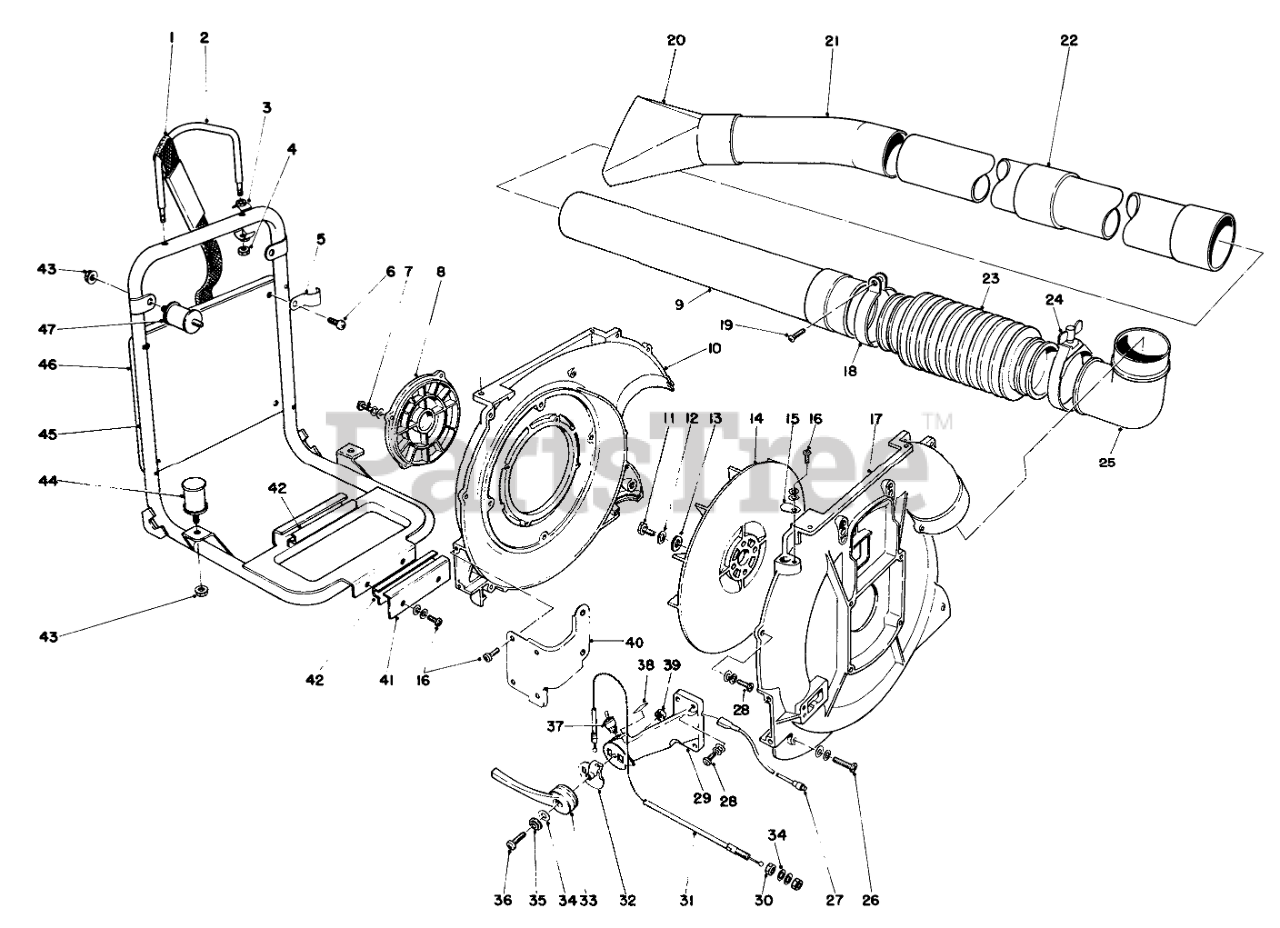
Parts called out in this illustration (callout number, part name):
1	Shoulder Strap
3	Adapter
4	Locknut
5	Bracket Cushion
6	SCREW-SHWH
7	Screw
8	Grid, Fan Case
9	STRAIGHT PIPE/SWIVEL
10	Fan Case, Operator Side
12	Lockwasher
13	WASHER
16	SCREW
17	Fan Case, Starter Side
18	Clamp
19	Screw
20	FAN HD NOZZLE
21	CURVED PIPE
22	Straight Pipe
23	FLEXIBLE PIPE
24	CLAMP
25	Elbow
27	Lead Switch
28	Screw
29	THROTTLE LEVER BRKT
31	THROTTLE CABLE
33	THROTTLE LEVER
34	Washer
35	Washer
36	SCREW
37	SWITCH
38	STOP SWITCH DECAL
40	Bracket
41	Bracket-Fuel Tank
42	Cushion-Fuel Tank
44	Cushion
45	Frame, Back Pack
46	Back Pack Pad
47	Cushion
